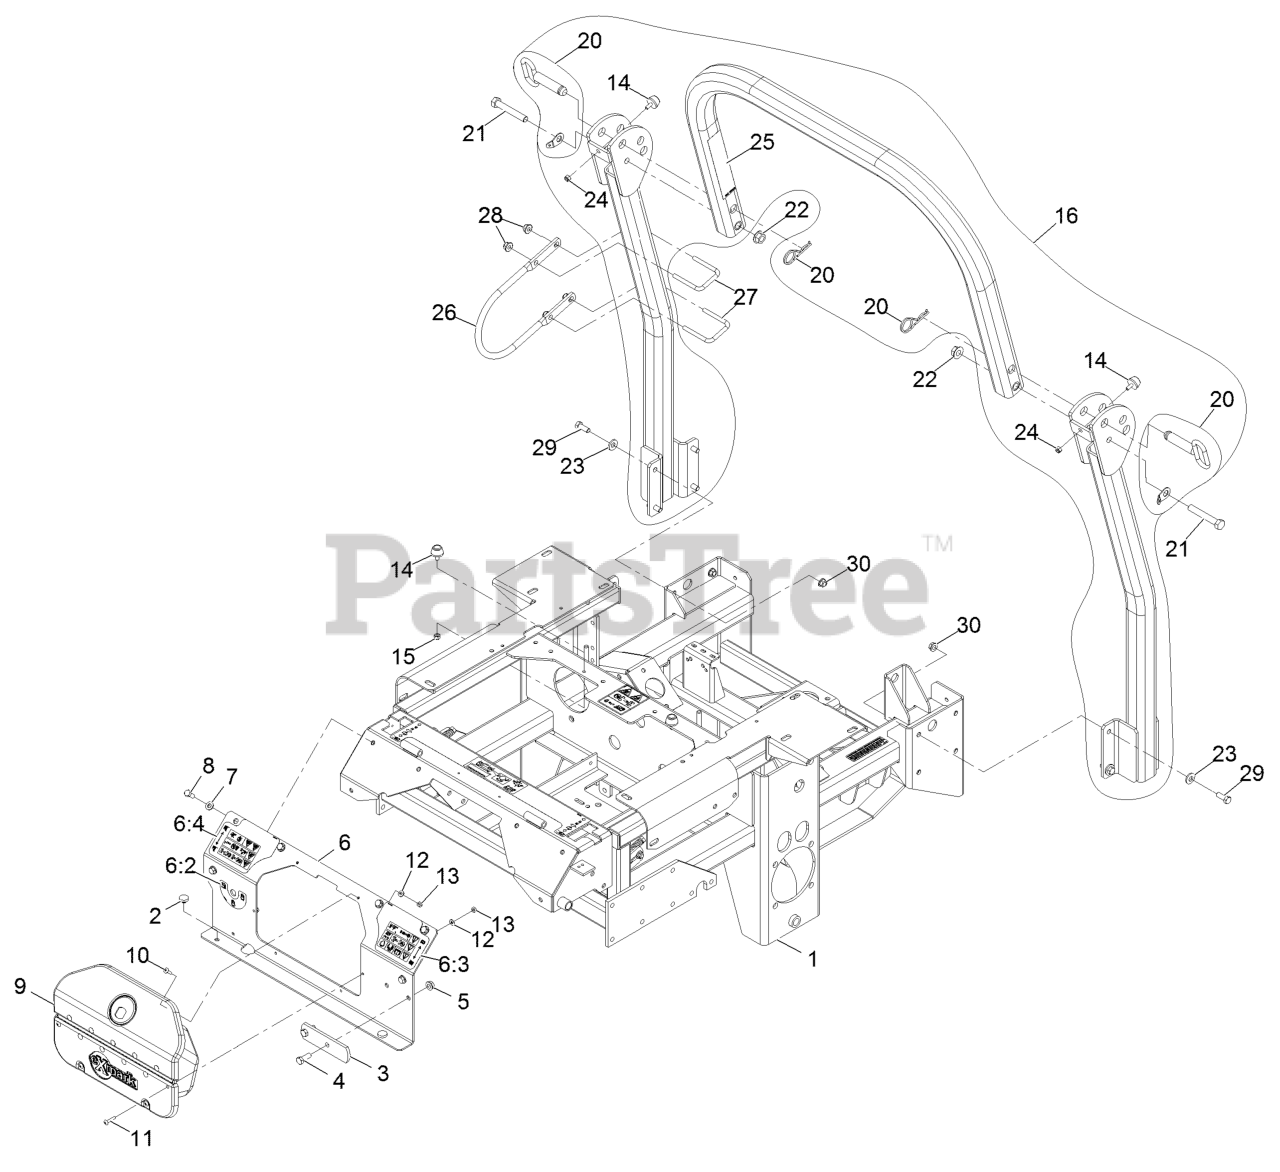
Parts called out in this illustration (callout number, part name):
1	ASM,KDXS ENGINE DECK W/DE
3	STOP-BRAKE, PARK
4	SCREW-HH
5	NUT-HHF, WHIZ
6	ASM, CONSOLE W/DECALS
6:2	Decal-Fuel
6:3	Decal-Console LH
6:4	Decal-Console RH
7	WASHER-PLAIN
8	SCREW-HH
9	ASM,CUBBY
10	SCREW-HEAD, TRUSS
12	WASHER-FLAT
13	NUT-LOCK, NI
14	BUMPER-RUBBER
15	NUT-LOCK, NI
16	KIT, 06 XS ROPS
20	PIN-FOLD, ROPS
21	SCREW-HH
23	WASHER-BELLEVILLE
24	NUT-LOCK, NI
25	DECAL-WARNING
28	NUT-HF, NI
29	SCREW-HH
30	NUT-HHF, WHIZ
